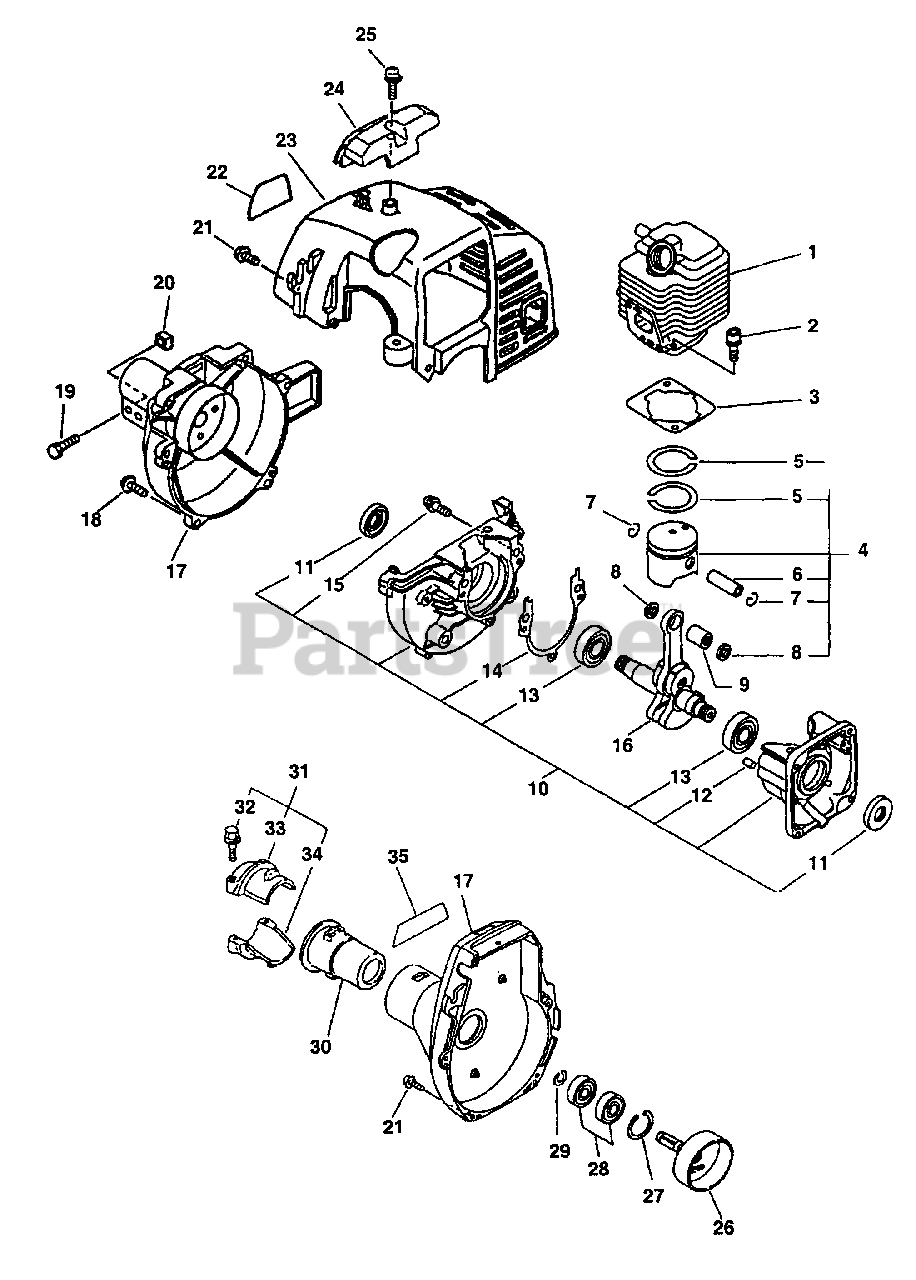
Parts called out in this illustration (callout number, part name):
1	CYLINDER
2	SCREW - 5X22
3	GASKET, CYLINDER
4	PISTON KIT
5	RING, PISTON
6	PIN, PISTON
7	RING, RETAINING
8	SPACER, PISTON
9	BEARING, NEEDLE
10	CRANKCASE KIT
11	SEAL, OIL
12	PIN - LOCATING
13	BEARING, BALL - 6201
14	GASKET, CRANKCASE
15	SCREW - 5X28
16	CRANKSHAFT ASSY
17	FAN CASE ASSY
17	CASE, FAN
18	SCREW - 4X18
19	BOLT - 5X28
20	NUT - 5 -- SQUARE
21	SCREW - 4X16
22	LABEL - MODEL GT-2400
23	COVER, ENGINE - GRAY
23	COVER, ENGINE
24	GUARD, TOP - GRAY
24	GUARD - TOP
25	SCREW - 5X16 -- TAPPING
26	DRUM, CLUTCH
27	RING, RETAINING - 28
28	BEARING, BALL - 6001
29	RING, RETAINING - 12
30	CUSHION
31	HOLDER KIT
32	BOLT - 5X25
33	CLAMP, MAIN PIPE - UPPER
34	CLAMP, MAIN PIPE - LOWER
35	LABEL - MODEL GT-2400
